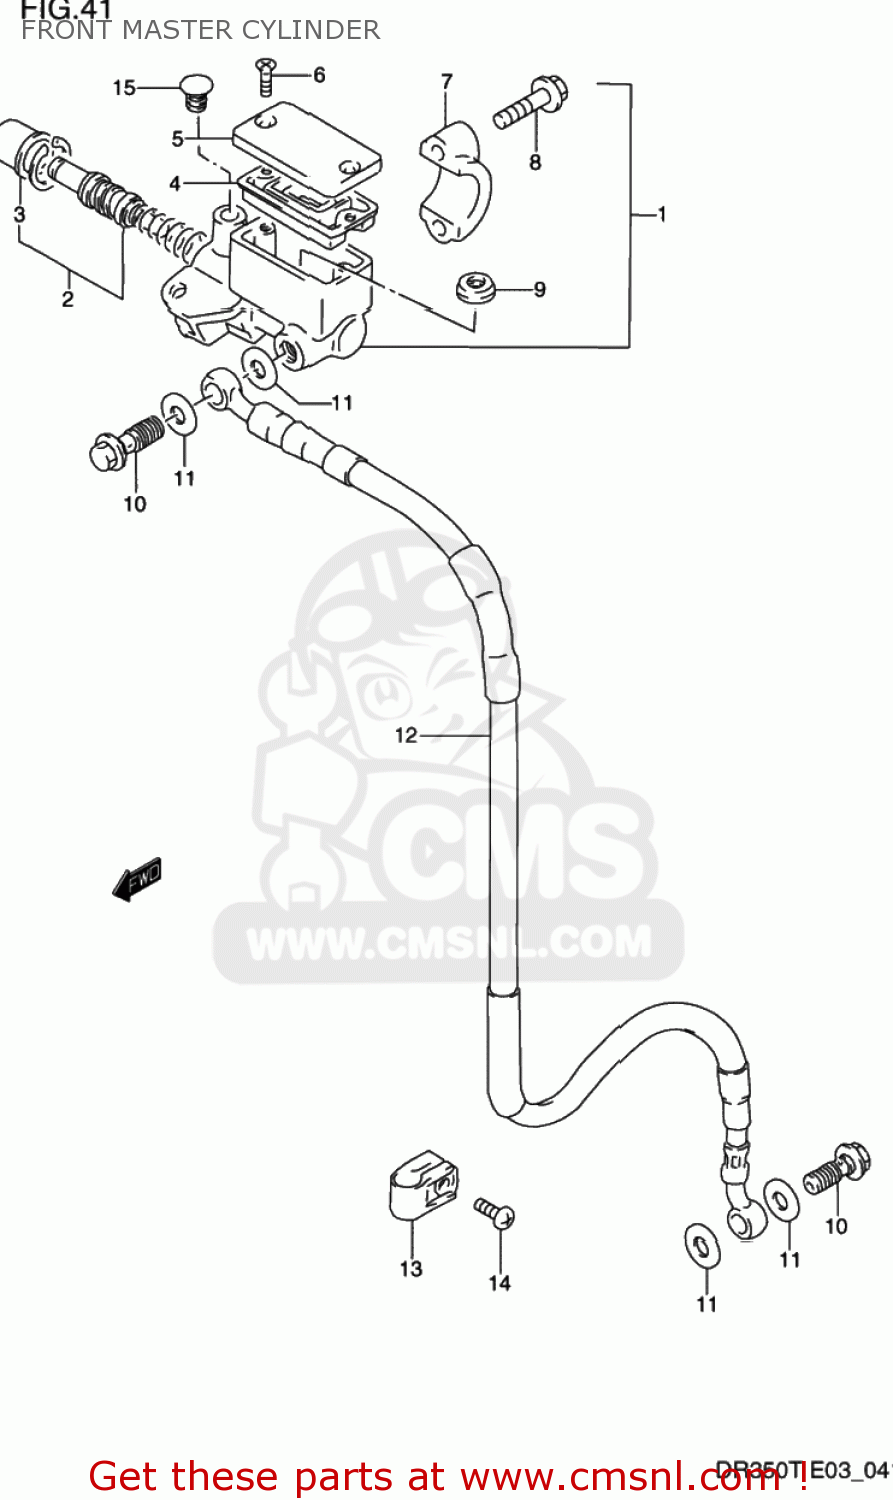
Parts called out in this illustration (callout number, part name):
1	CYLINDER ASSEMBLY,FRONT MASTER
2	PISTON & CUP SET
3	BOOT
4	DIAPHRAGM
5	CAP
6	SCREW
7	HOLDER
8	BOLT
9	SEPARATOR
10	BOLT UNION
11	WASHER(10X15X1.5)
12	HOSE,FR BRAKE
13	CLAMP,FR BRAKE HOSE
14	SCREW
15	CAP(OD:14)
